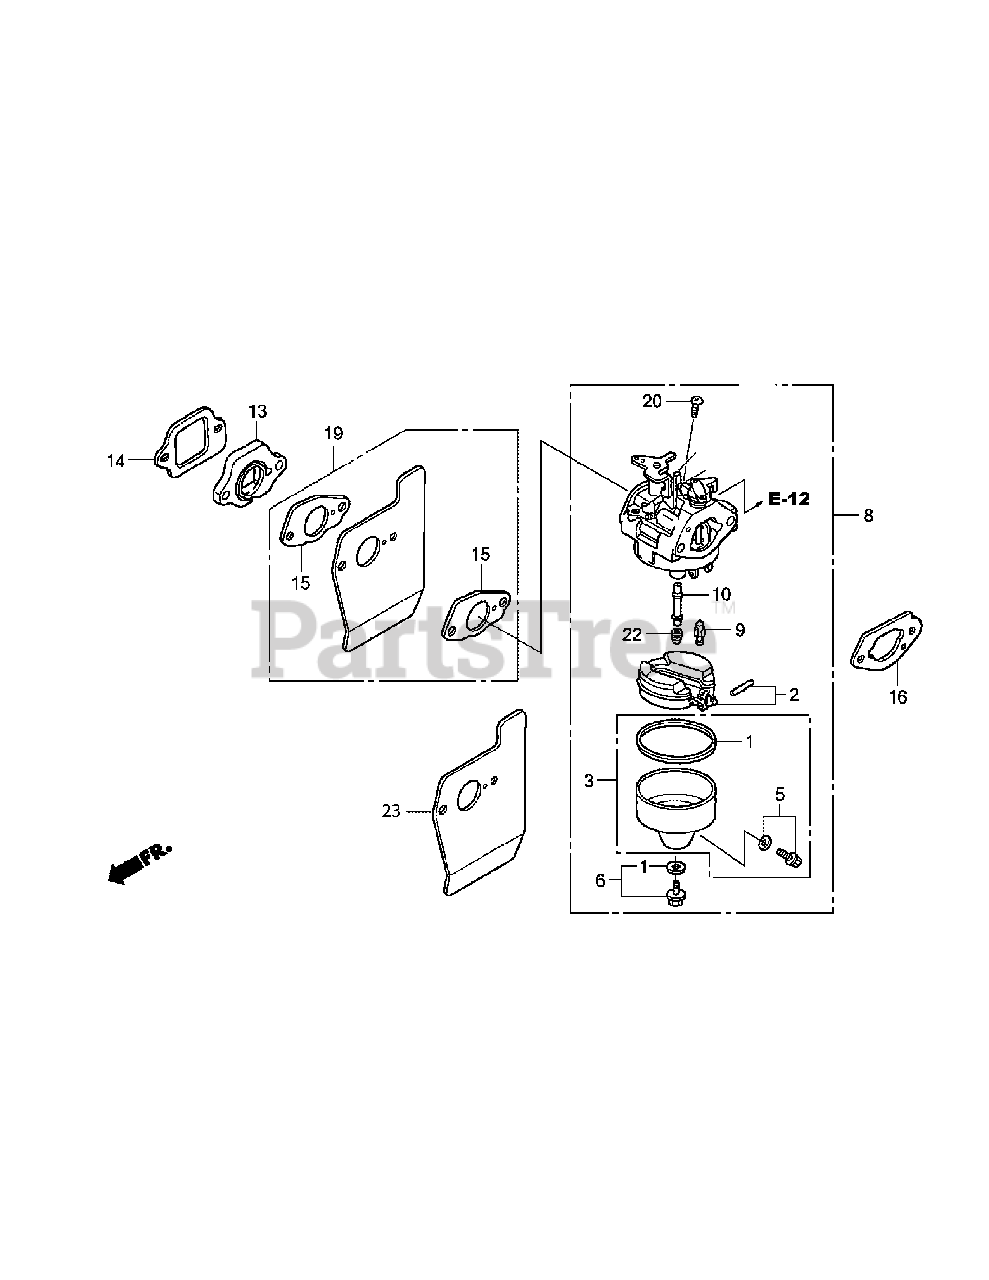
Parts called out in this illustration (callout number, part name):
1	Gasket Set
3	Float Chamber Set
8	Carburetor Ass’ly (to 1854820)
8	Carburetor Ass’ly (from 1854821)
9	Float Valve
10	Main Nozzle
13	Carburetor Insulator
14	Insulator Gasket
16	Carburetor Gasket
20	Pan Screw, 5 x 6
22	Main Jet, #60
22	Main Jet, #62
22	Main Jet, #65
